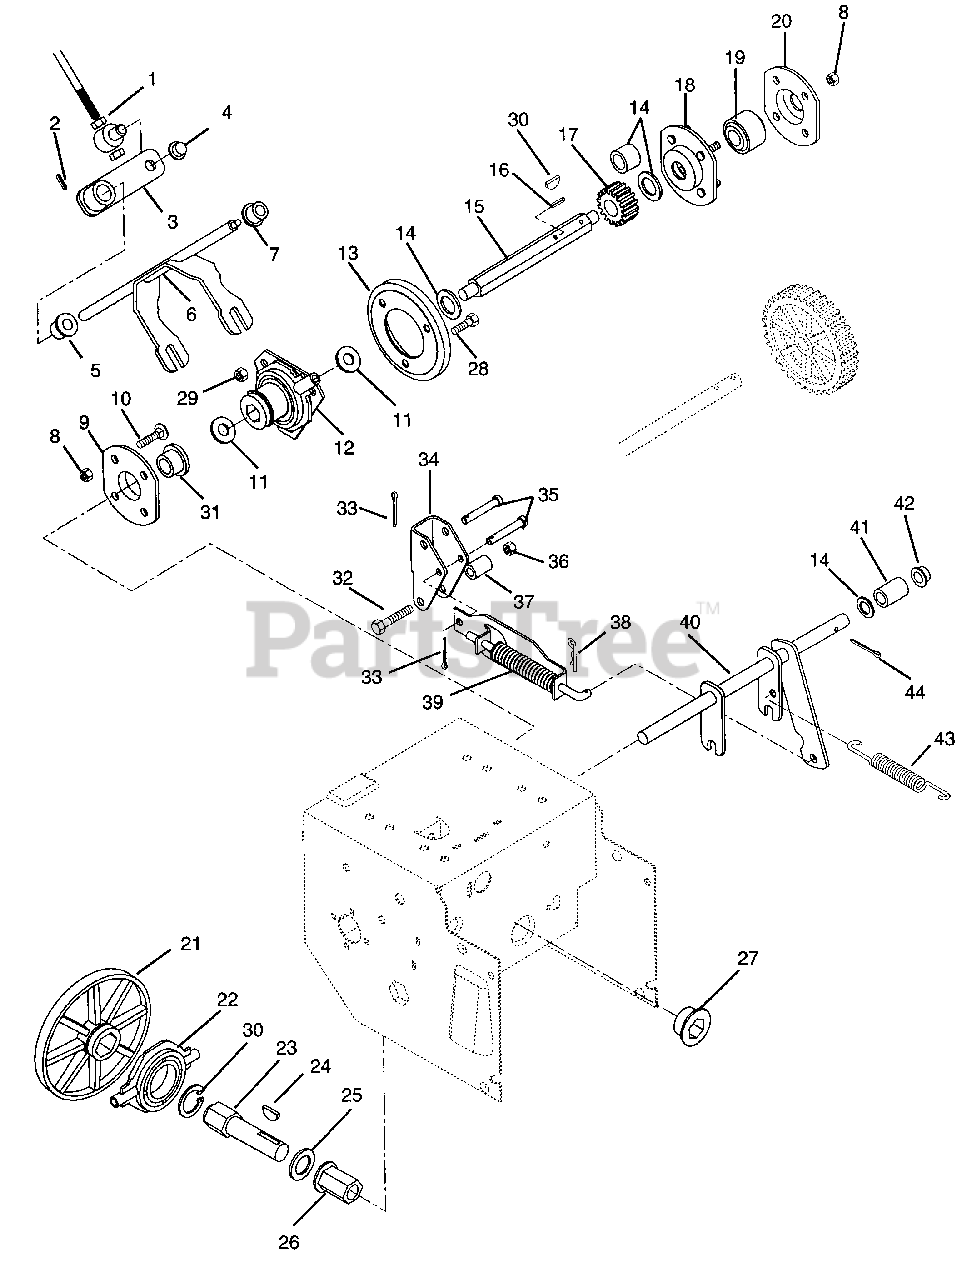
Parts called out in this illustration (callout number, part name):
2	PIN-ROLL .156X.88
3	ARM-SPEED CHANGE
4	CAP, 3/8 ROD YWZC
5	BSHG-FLG.500X.625X.312X.750NY
6	FORK-SPEED
7	BSHG-FLG .325X.444X.440X.560
8	NUT-LK-DUAL FACE 10-24 YWZC
9	BUSHING FLANGE
10	BLT-RDHDSQSHK #10-24X.38 GR2YW
11	WSHR-FL-STL .505X1.00X.062YWZC
12	SHIFT CARRIER
13	FRICTION DISC
14	@WSHR-FL-STL.531X1.06X.095YWZC
15	HEX SHAFT
16	PIN-ROLL .125X.88
18	BEARING FLANGE
19	BRG-BALL .500X1.375X.437
20	BEARING FLANGE
21	FRICTION PLATE
22	BEARING ASSEMBLY
23	HEX SHAFT
24	KEY-WDRF .188X.75X.313 SAE 9
25	WSHR, THRUST .625X1.125X.063
26	BSHG-FLG .625X.875X1.750X1.188
27	BSHG-FLG .875X1.25X.75X1.50HX
28	@BLT-HEX .25-20X.50 GR5 YWZC
29	@NUT-LK-CTR .25-20 YWZC
30	RG-RTNG-EXT 1.250X.050
31	BSHG-FLG .500X.750X.625X.937
32	@BLT-HEX .31-18X1.50 GR5 YWZC
33	@PIN-CTR .09X.50 EXTPRSQCT YWZ
34	BRACKET
35	PIN, CLEVIS .243/.248X1.50 YWZ
36	@NUT-LK-CTR .31-18 YWZC
37	SPACER -SPLIT .340X.490X1.02
38	PIN-HAIR INT .08X.18X1.18 YWZC
39	TRACTION CLUTCH ASSY
40	CLUTCH FORK
41	SPACER .504X.748X.321
42	CAP, .50 ROD YWZC
43	SG-TENS .063X.44X1.56
44	@PIN-CTR .12X1.00 EXTPRSQCT YZ
